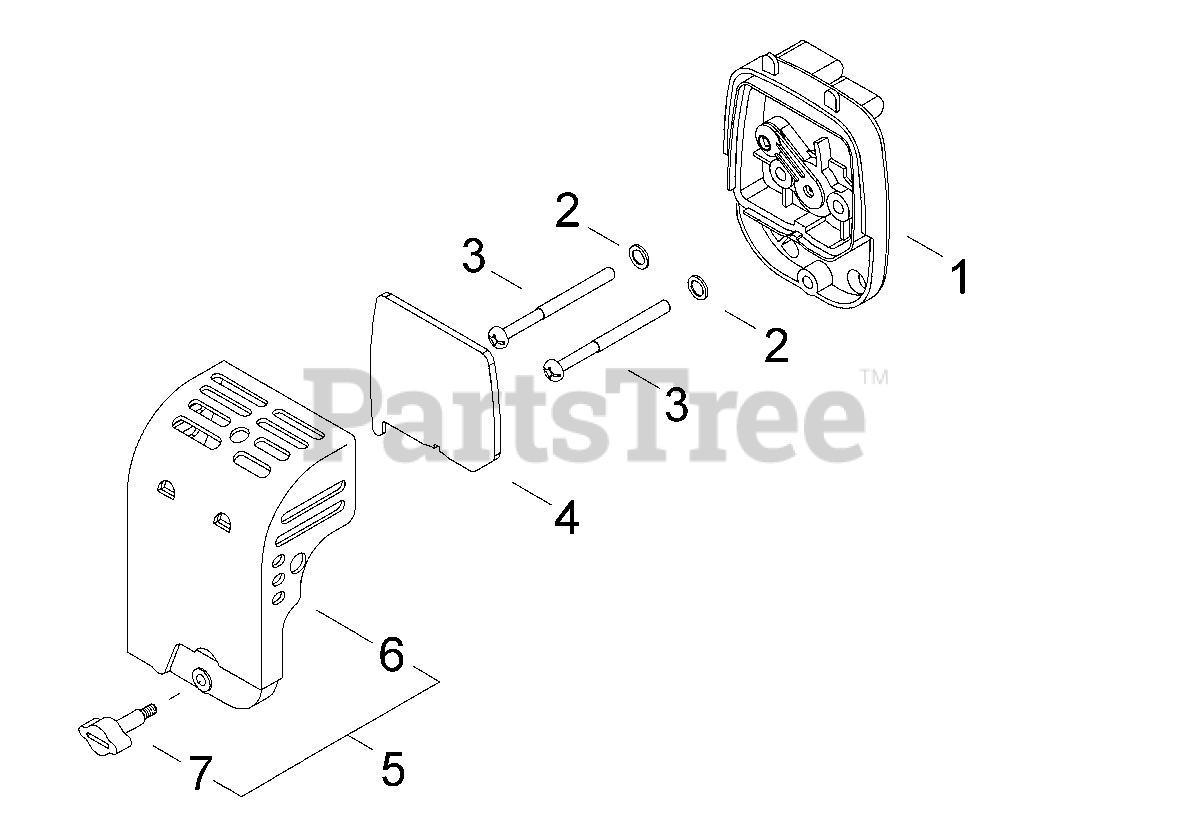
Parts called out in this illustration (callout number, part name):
1	CASE, AIR FILTER
2	WASHER - 5
3	SCREW - 5X60
4	FILTER, AIR
5	AIR FILTER COVER ASSY
6	COVER, AIR FILTER
7	THUMBSCREW
